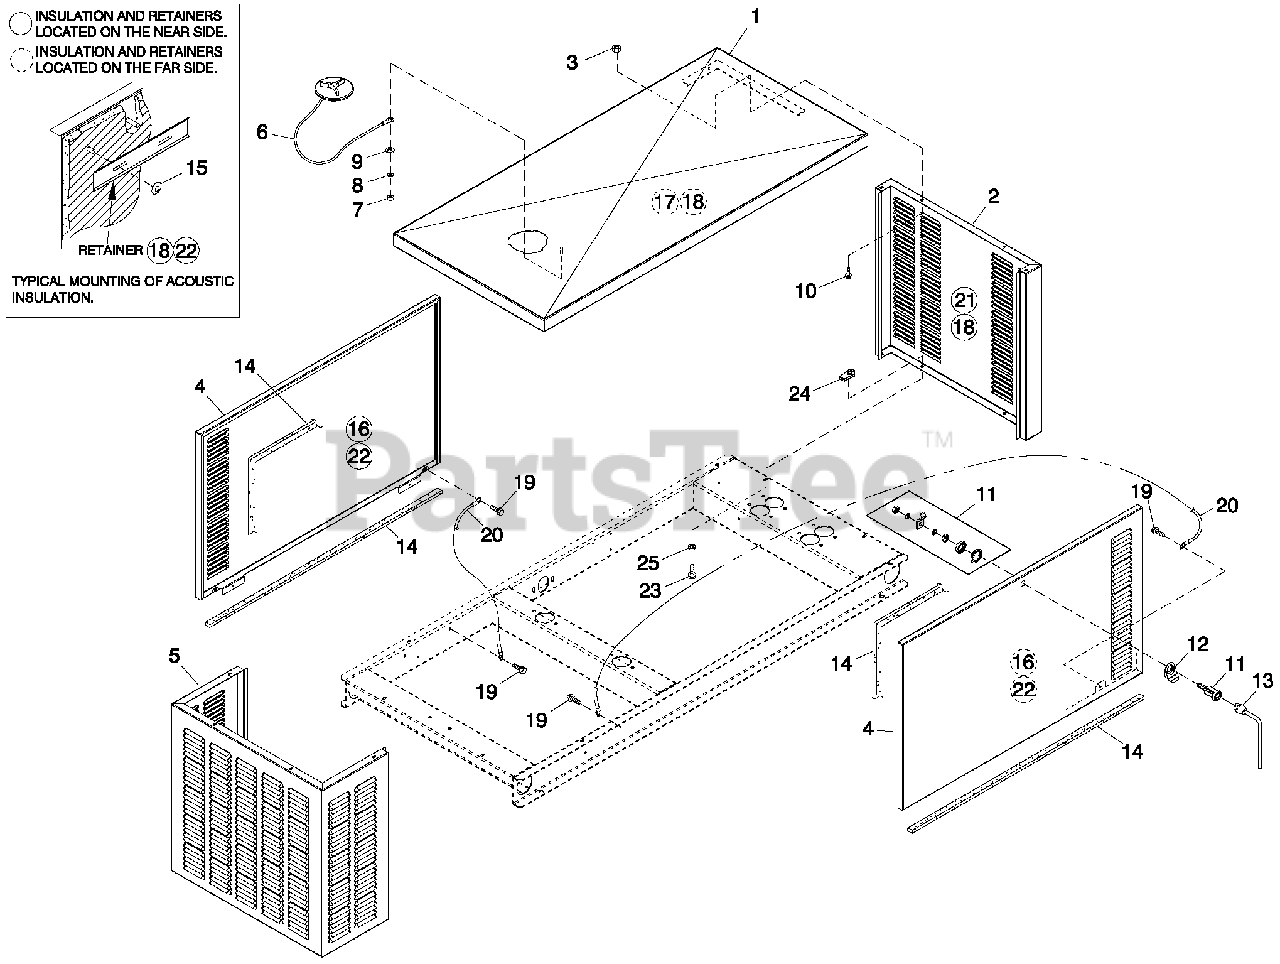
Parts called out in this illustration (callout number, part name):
1	ROOF 1.6L C1
2	REAR INTAKE WRAP 1.6L C1
3	NUT HEX LOCK M6-1.0 SS NY INS
4	DOOR LEFT/RIGHT SIDE 1.6L C1
5	FRONT DISCHARGE WRAP 1.6L C1
6	ASSY ACCESS COVER
7	NUT HEX 1/4-20 STEEL
8	WASHER LOCK M6-1/4
9	WASHER FLAT 1/4-M6 ZINC
10	SCREW THF M6-1 X 16 N WA Z/JS
11	VISE-ACTION LATCH, SLOTTED CIR
12	TAB PULL
13	KEY VISE-ACTION LATCH,SLOT CIR
14	FOAM STRIP 3/4"WIDE X 3/16"THK (294" LG)
15	WASHER SELF LOCKING DOME
16	INSULATION SIDE DOOR C1
17	INSULATION ROOF C1
18	RETAINER INSULATION (450)
19	SCREW HWHTF M6-1.0 X 16
20	ASSY WIRE 14AWG GRN/YEL (32.25"LG)
21	INSULATION REAR C1
22	RETAINER INSULATION (820)
23	SCREW HHFC M6-1.0 X 20 G8.8
24	NUT SPRINGCLIP M6-1.0
25	WASHER LOCK M6-1/4
